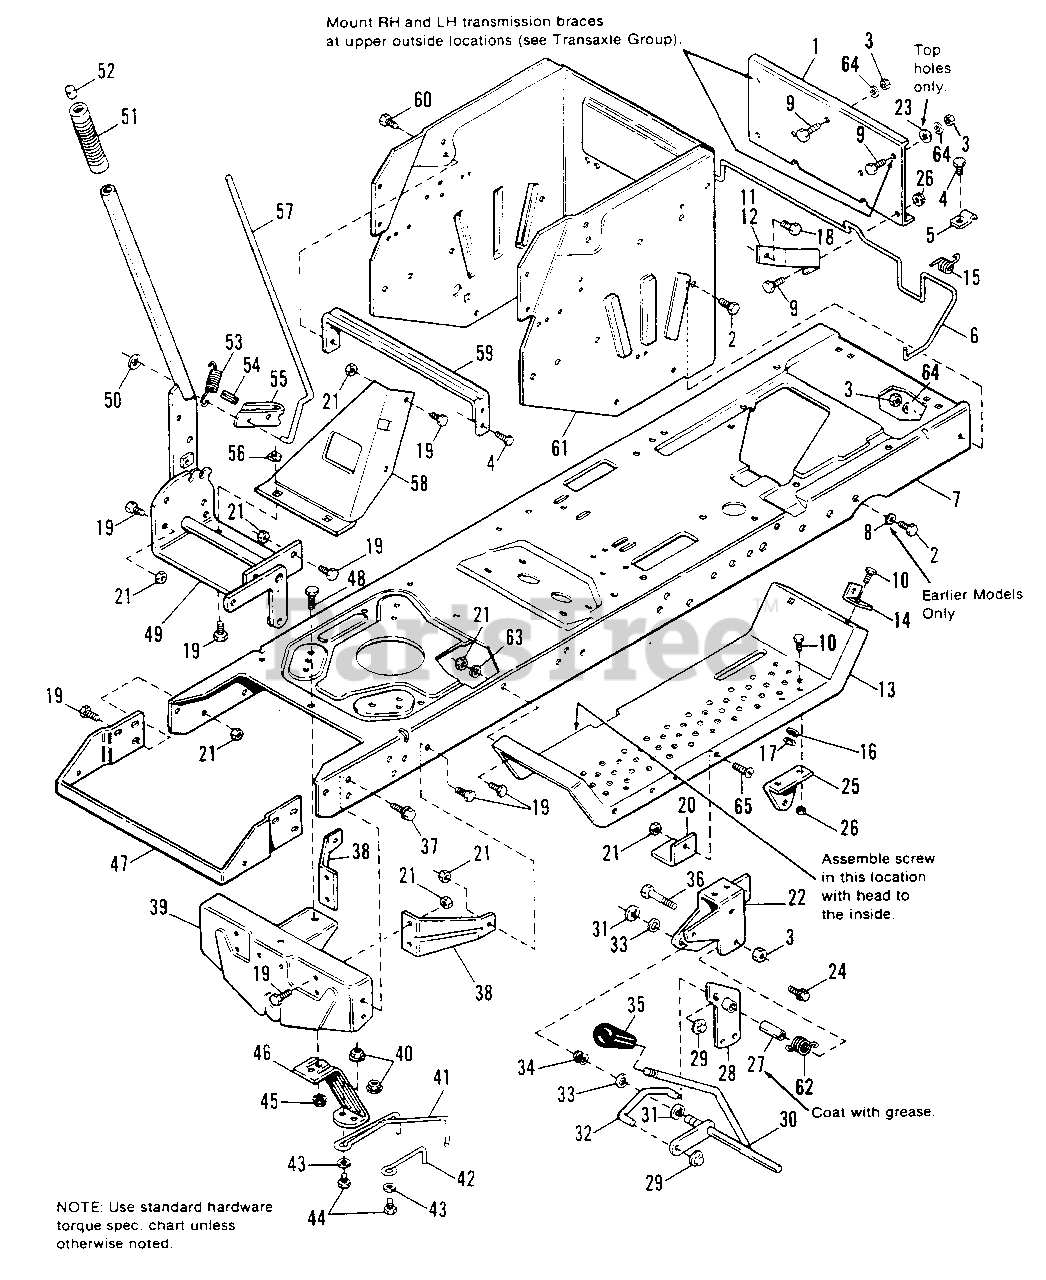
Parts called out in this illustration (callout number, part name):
2	CAPSCREW, 3/8-16 x 1
3	NUT, Hex, 3/8-16
4	SCREW, Taptite, 5/16-18 x 1/2
6	ROD, Seat Latch
8	LOCKWASHER, 3/8 Ext. Tooth (*Early Models Only)
9	CAPSCREW. 3/8-16 x 1-1/4"
10	CAPSCREW, 1/4-20 x 5/8
11	BRACE, Drawbar, L.H.
12	BRACE. Drawbar, R.H.
14	BRACKET, Seat Latch
15	SPRING Torsion
16	WASHER, Plain, 1/4 Std.
17	NUT, Hex, 1/4-20
18	SCREW, Taptite, 3/8-16 x 3/4
19	CAPSCREW, 5/16-18 x 3/4
20	UP-STOP, Mower
21	NUT, Hex, 5/16-18
22	BRACKET, PTO Lever Mtg.
24	SCREW, Taptite, 1/4-20 x 1/2
25	SUPPORT, PTO Lever
26	NUT, Hex, Whiz Flange, 3/8-16
28	ARM ASSY, PTO Link
29	NUT, Pal, 3/8
30	LEVER ASSY., PTO
31	RING, Snap
32	LINK, PTO
34	BUSHING Split (Nylon)
35	KNOB
36	CAPSCREW, 3/8-16 x 2-1/4
37	SCREW, Taptite, 5/16-18 x 3/4
38	BRACE, Axle Support
39	SUPPORT ASSY., Axle
40	NUT, Hex, Flange Lock, 5/16-18
43	WASHER, Plain, 1/4 Std.
44	CAPSCREW, 5/16-18 x 7/8
45	NUT, Whiz Flange, 5/16-18
46	SUPPORT, Belt Guide
47	SUPPORT, Hood
48	CAPSCREW, Whiz Flange, 5/16-18 x 1-1/4
49	LEVER ASSY., Lift
50	NUT, Push On
51	GRIP
54	PIN, Spring, 3/8 x 1
55	LATCH, Lift Lever
56	NUT, Speed, 5/16-18
58	BRACE, Lift Lever
59	BRACE, Seat (Wrapper)
60	SCREW, Taptite, 5/16-18 x 1
61	SUPPORT, Axle (Wrapper
62	SPRING, Torsion
63	LOCKWASHER, 5/16
64	LOCKWASHER, 3/8
65	SCREW, Slotted, 5/16-18 x 3/4
